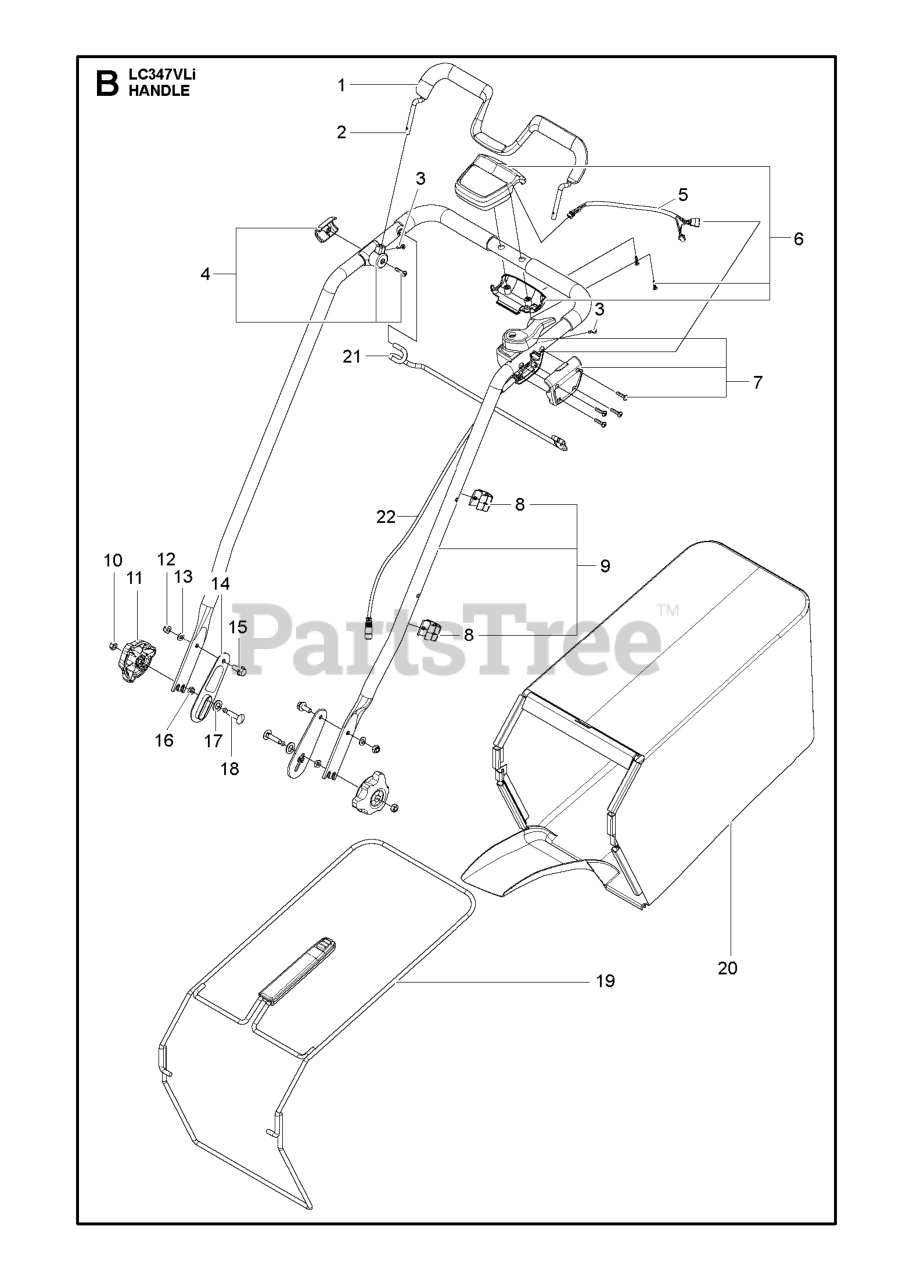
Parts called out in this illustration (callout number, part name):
1	GRIP HANDLE ASSY OPC BAIL
2	BAIL HANDLE ASSY OPC BAIL
3	DRIVE SCREW HANDLE ASSY M4 BAI
4	BAIL ARM ASSY SPARE PART ASSY
5	EXTENSION CABLE CONTROL PANEL
7	SWITCHBOX ASSY SPARE PART ASSY
8	CABLE HOLDER HANDLE ASSY
10	NUT
11	Knobs
12	LOCKNUT M8
13	WASHERS
14	Washers
15	BOLT
16	NUT ML6M M8
17	Washers
18	Bolts
21	Bails
